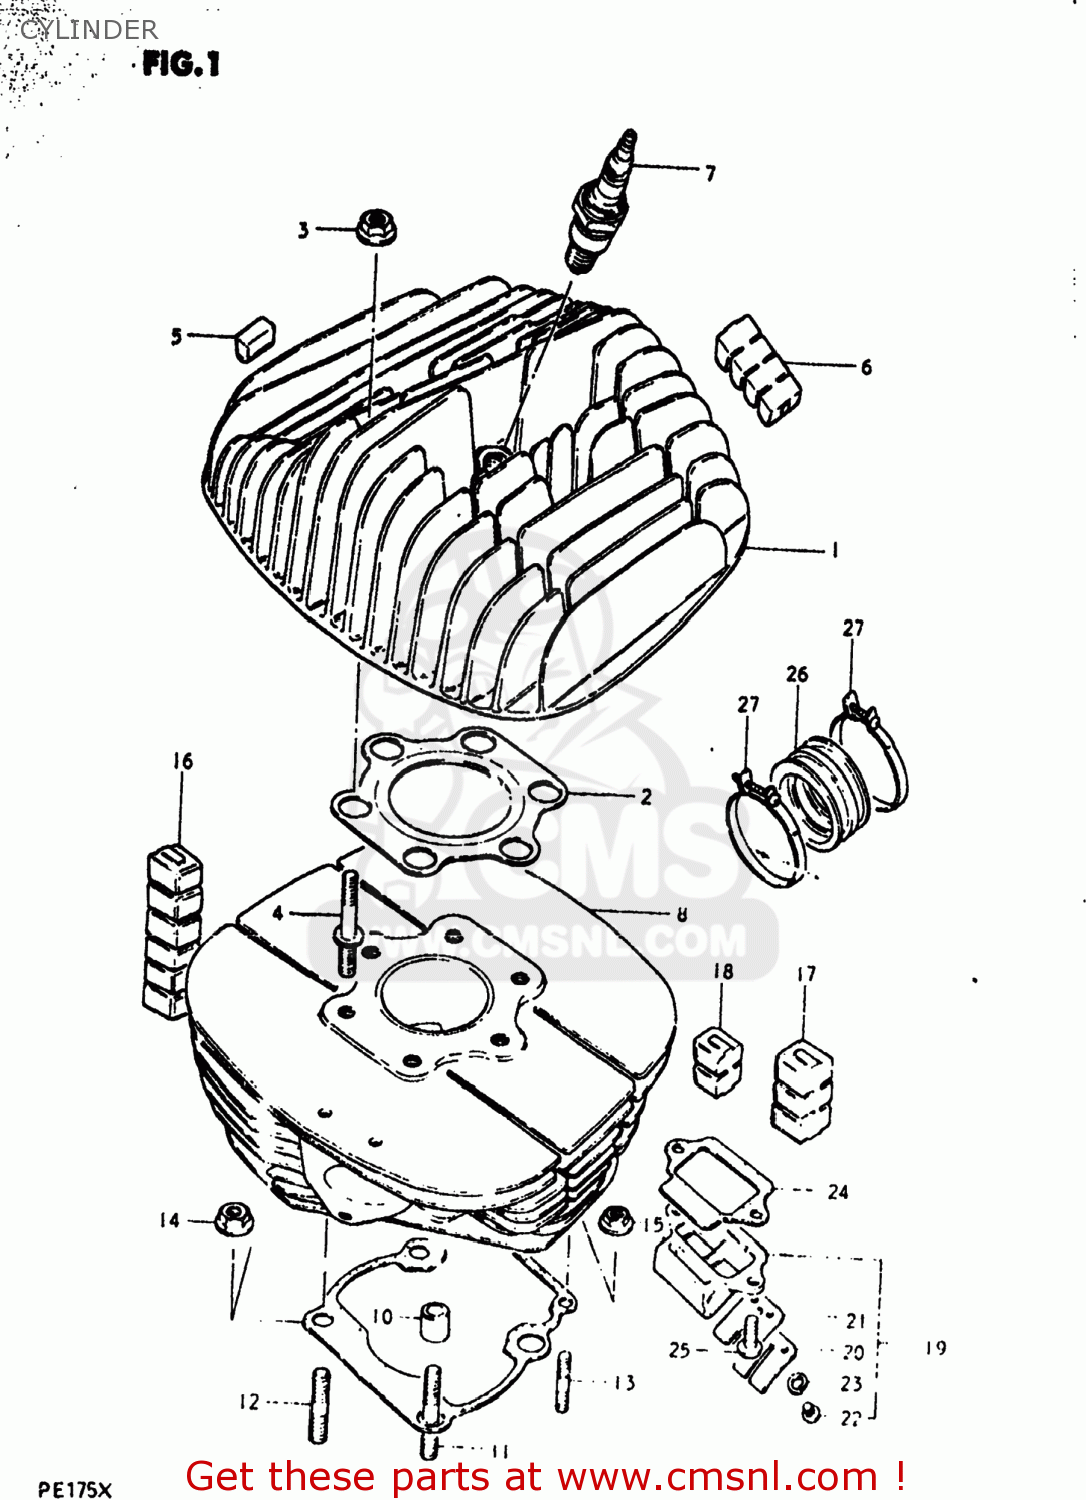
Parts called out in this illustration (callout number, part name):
1	HEAD,CYLINDER
2	GASKET,CYLINDER HEAD (NAS)
3	NUT
4	BOLT,STUD
5	PAD,CYLINDER
6	PAD,CYLINDER
7	PLUG,SPARK(B10EGV)
8	CYLINDER
9	GASKET,CYLINDER (MCA)
10	PIN
11	STUD 8X40
12	STUD 8X25
13	STUD 6X20
14	NUT
15	NUT
16	PAD,CYLINDER
17	PAD,CYLINDER
18	PAD,CYLINDER
19	VALVE ASSY,REED
20	STOPPER,REED VALVE
21	VALVE,REED
22	SCREW
23	LOCK WASHER
24	GASKET,REED VALVE (MCA)
25	SCREW
26	PIPE,INTAKE
27	CLAMP
